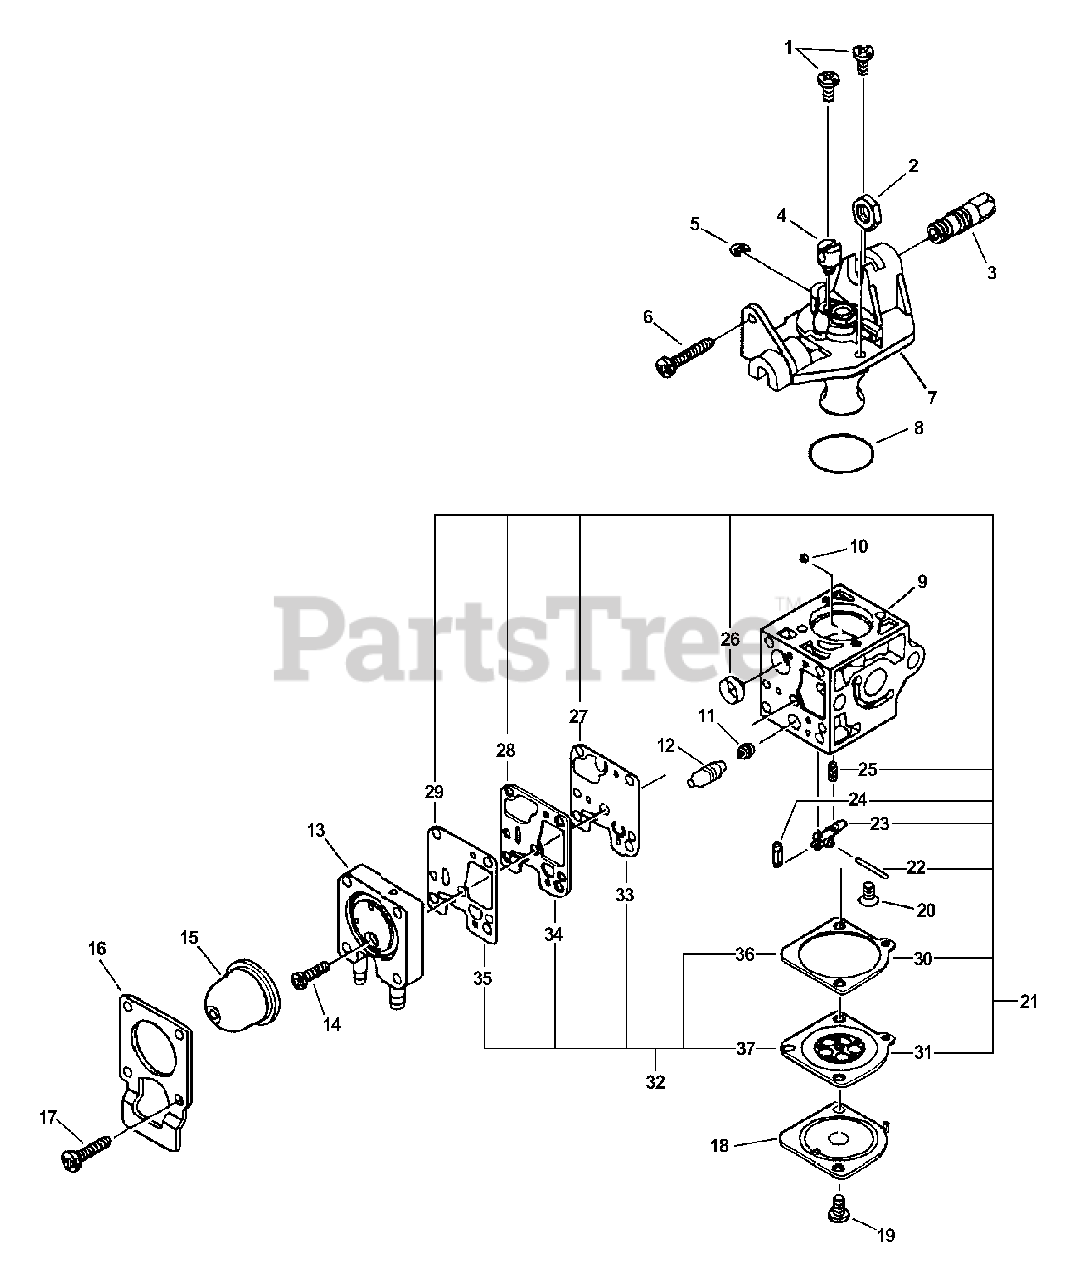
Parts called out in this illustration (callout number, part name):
3	NUT, CABLE ADJUST
5	RING, RETAINING
6	SCREW, IDLE ADJUST
7	ROTOR COVER ASSY
9	BODY, CARBURETOR
10	GUIDE, ROLLER
12	PLUG KIT
13	BASE, PURGE
14	SCREW, PURGE BASE
15	BULB, PURGE
16	RETAINER, PURGE BULB
17	SCREW, RETAINER
18	COVER, METERING
20	SCREW, METERING LEVER PIN
21	REPAIR KIT
22	PIN, METERING LEVER
23	LEVER, METERING
24	VALVE, INLET NEEDLE
25	SPRING, METERING LEVER
26	STRAINER
27	DIAPHRAGM, PUMP
28	GASKET, PUMP
29	DIAPHRAGM, SURGE
30	GASKET, DIAPHRAGM
31	DIAPHRAGM, METERING
32	DIAPHRAGM/GASKET KIT
33	DIAPHRAGM, PUMP
34	GASKET, PUMP
35	DIAPHRAGM, SURGE
36	GASKET, DIAPHRAGM
37	DIAPHRAGM, METERING
